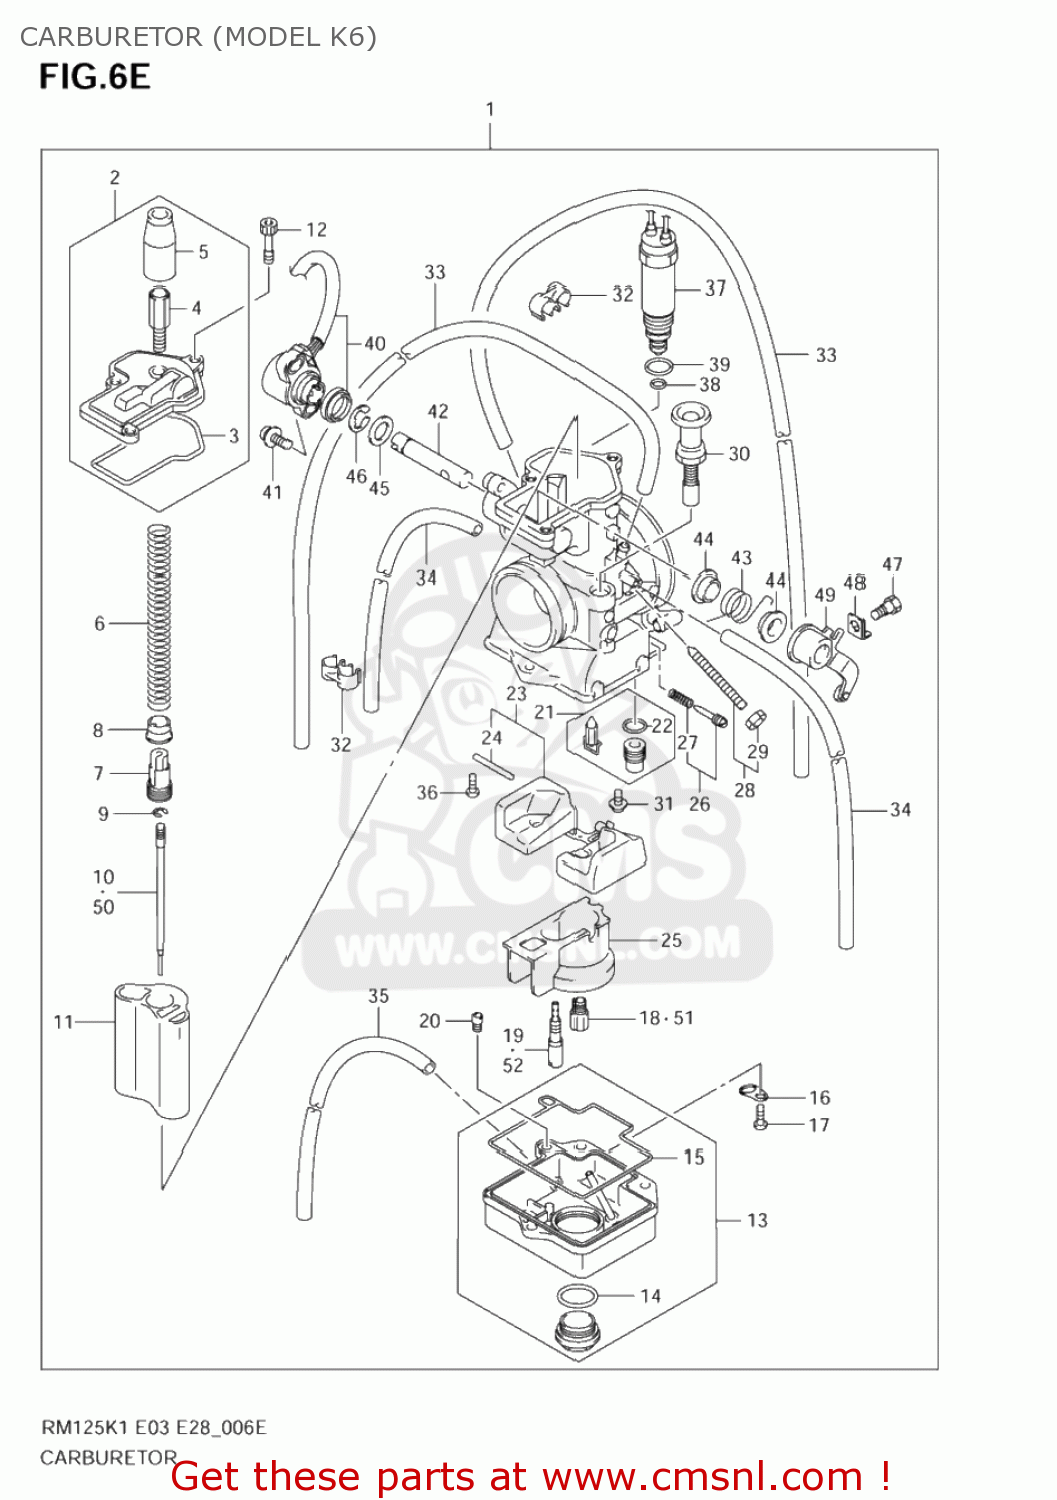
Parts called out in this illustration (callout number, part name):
1	CARBURETOR ASSY
2	TOP CAP ASSY
3	O RING
4	CAP
5	ADJUSTER,CABLE
6	SPRING
7	GUIDE HOLDER
8	RING
9	E RING,MULTIPLE JET NOZZLE
10	NEEDLE(6BGY23-75)
11	VALVE,PISTON
12	BOLT
13	FLOAT BODY ASSY
14	O RING
15	O RING
16	PLATE,CARBURETOR
17	SCREW(5X14)
18	JET,MAIN(370)
19	JET,PILOT(42.5)
20	JET,ENRICHMENT(55)
21	VALVE ASSY,NEEDLE
22	O RING,NEEDLE VALVE SEAT
23	FLOAT SET
24	PIN,FLOAT
25	HOLDER
26	ADJUSTER SET(AS)
27	SPRING
28	ADJUSTER SET (PV)
29	NUT
30	PLUNGER ASSY
31	SCREW
32	CLIP
33	HOSE(3.5X6.5X600)
34	HOSE(3.5X6.5X600)
35	HOSE(3X5X600)
36	SCREW
37	SOLENOID ASSY
38	O RING
39	O RING
40	SENSOR ASSY
41	SCREW
42	SHAFT
43	TORSION SPRING
44	RING
45	GASKET,THROTTLE SHAFT (NAS)
46	E RING
47	BOLT
48	PLATE
49	LEVER ASSY
50	NEEDLE(6CHY17-64)
51	JET,MAIN(400)
52	JET,PILOT(25)
53	WASHER,JET NEEDLE CLIP
54	HOLDER,GUIDE
